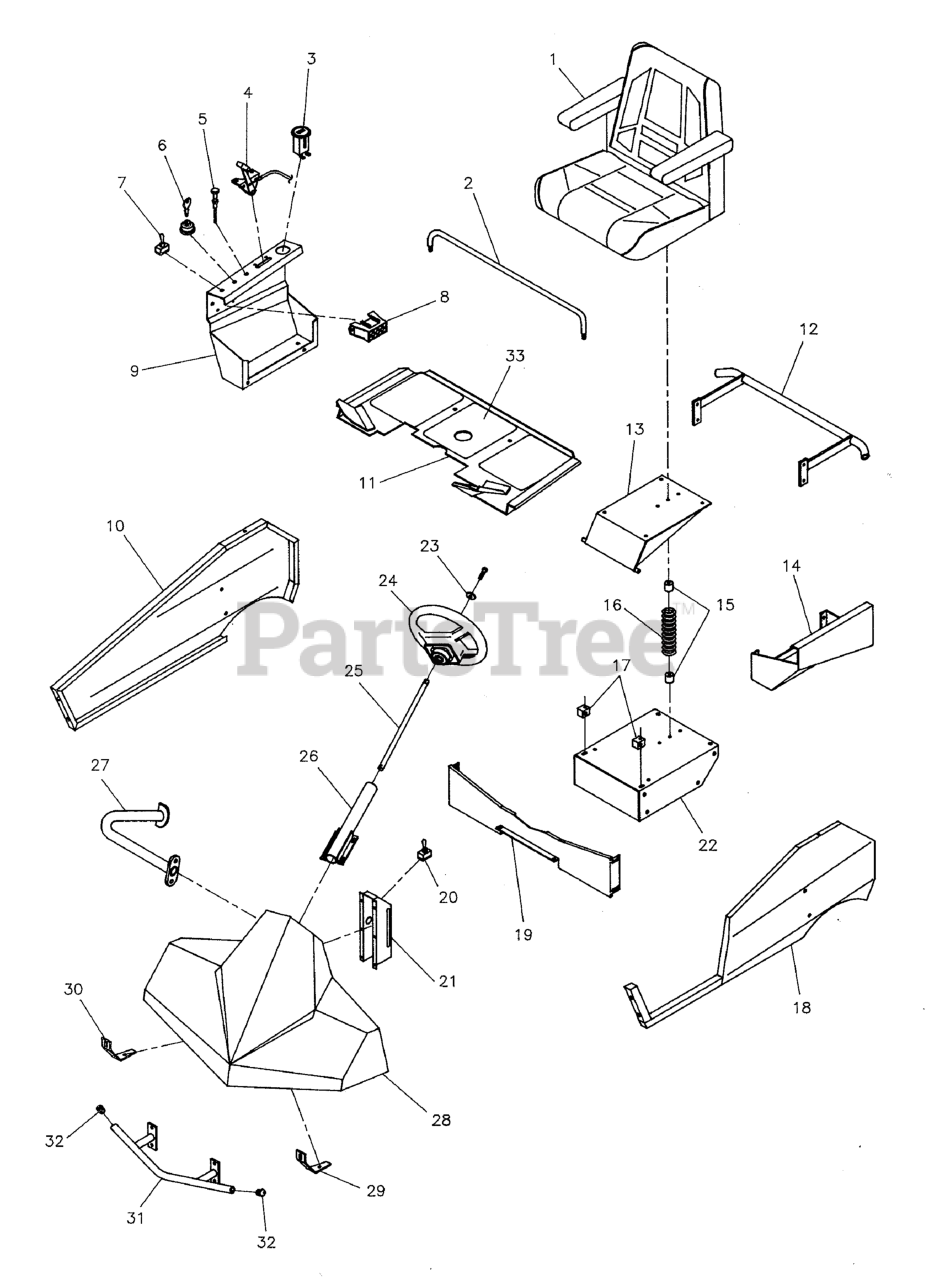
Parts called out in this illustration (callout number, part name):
1	SEAT, Black & Silver, Complete
2	Side Panel Support
3	HOUR METER
4	CABLE, Throttle, 38"
5	CABLE, CHOKE CONTROL, 45
6	SWITCH, Ignition
7	SWITCH, Electric Clutch
8	Fuse Block
9	Control Panel Weldment
10	Side Panel Right
11	Floor Board Weldment
12	Rear Bumper Weldment
13	Seat Plate Weldment
14	Tool Box Weldment
15	Rubber Bumper
16	SPRING, SUSPENSION
17	Seat Mount Block
18	Side Panel Left
19	Body Gusset Weldment
20	SWITCH, Actuator
21	Switch Column
22	Seat Mount Plate Weldment
23	Steering Wheel Washer
24	Steering Wheel
25	Steering Shaft
26	Steering Tube Weldment
27	Side Body Arm Weldment
28	Cowl Weldment
29	Front Cowl Mount - Left
30	Front Cowl Mount - Right
31	Front Bumper Weldment
32	End Plug
